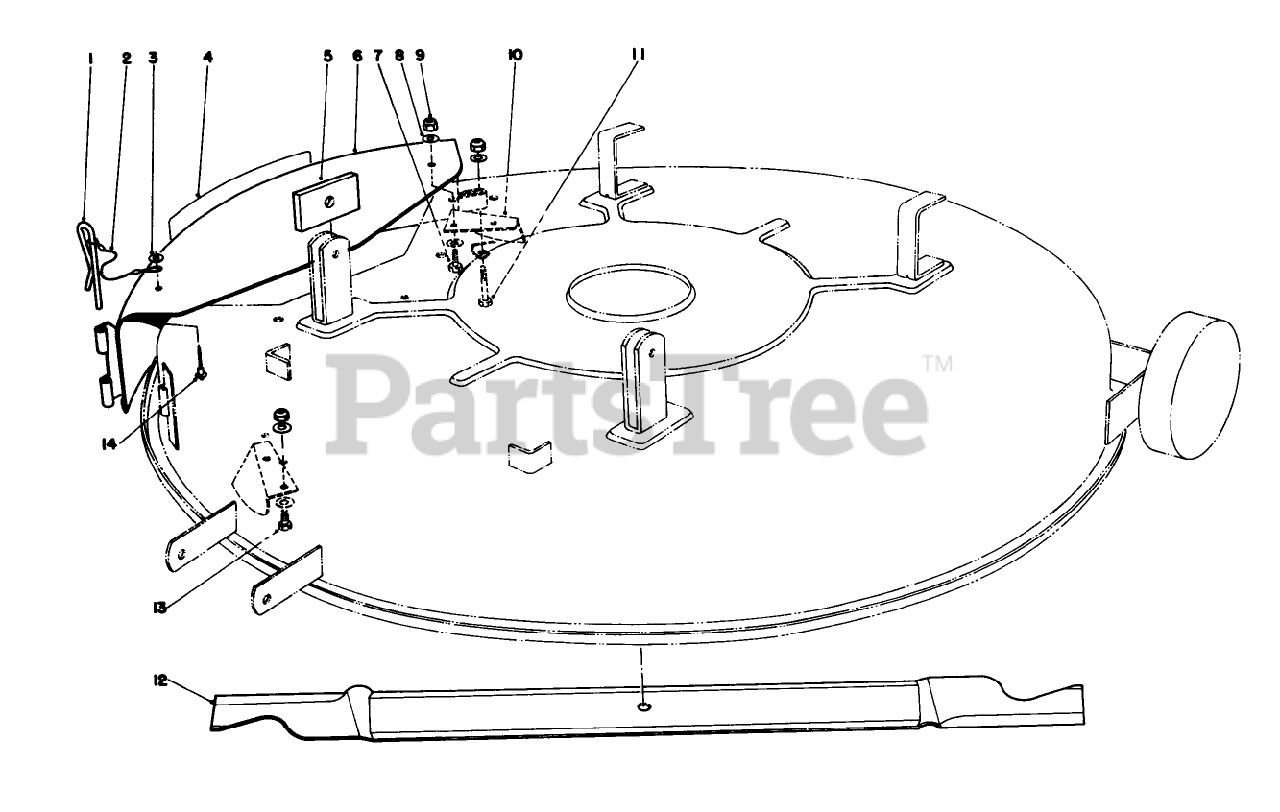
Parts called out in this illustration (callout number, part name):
1	PIN-LOCKING, CHUTE
2	LANYARD
3	Washer
6	MULCHER COVER ASM (BLACK)
7	SCREW-HH
8	WASHER-PLAIN
9	NUT-LOCK, NI
10	KICKER *B
11	SCREW-HH
13	SCREW-HH
14	RIVET-BLIND
